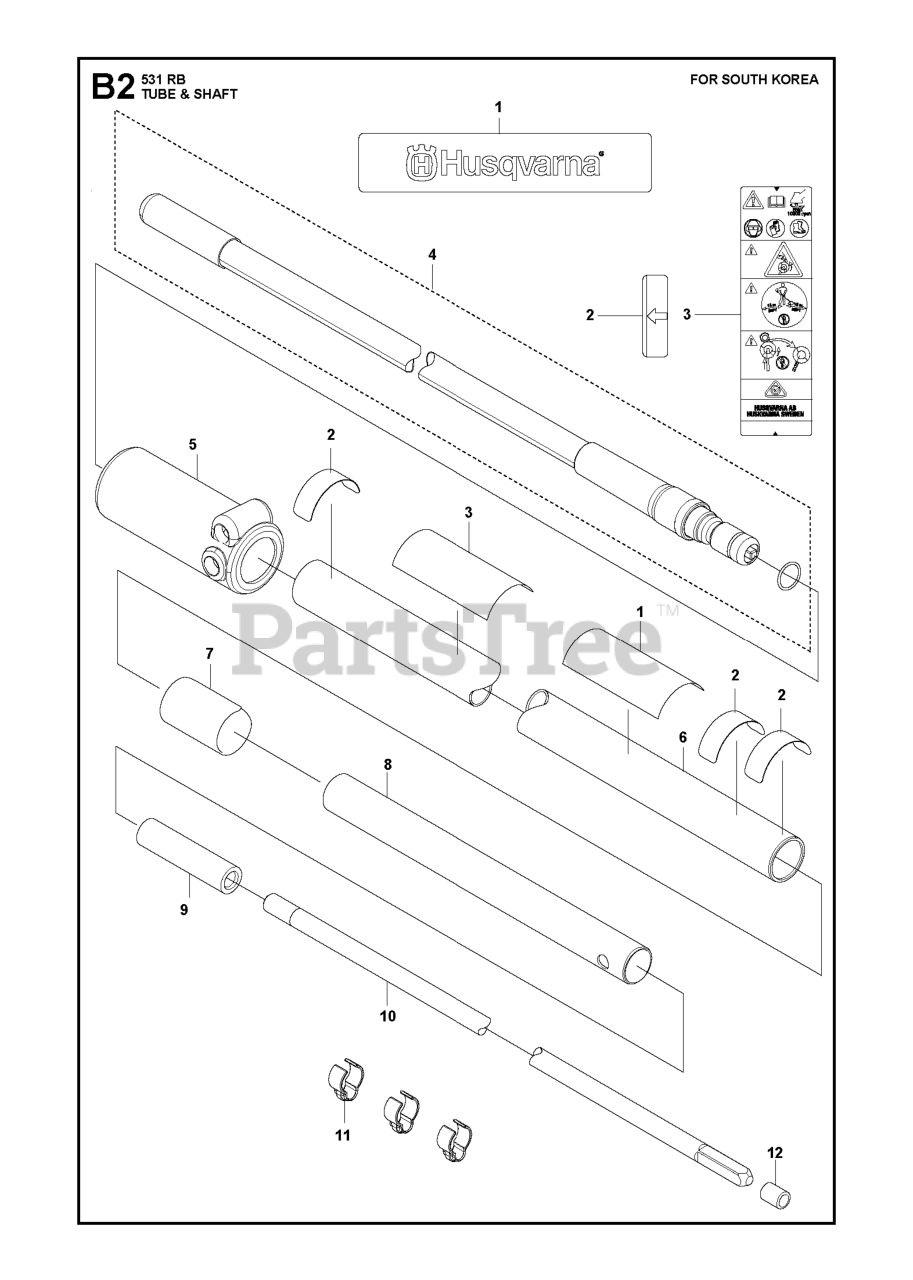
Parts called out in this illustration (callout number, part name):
2	LABEL
11	CLAMP
12	SPACER
